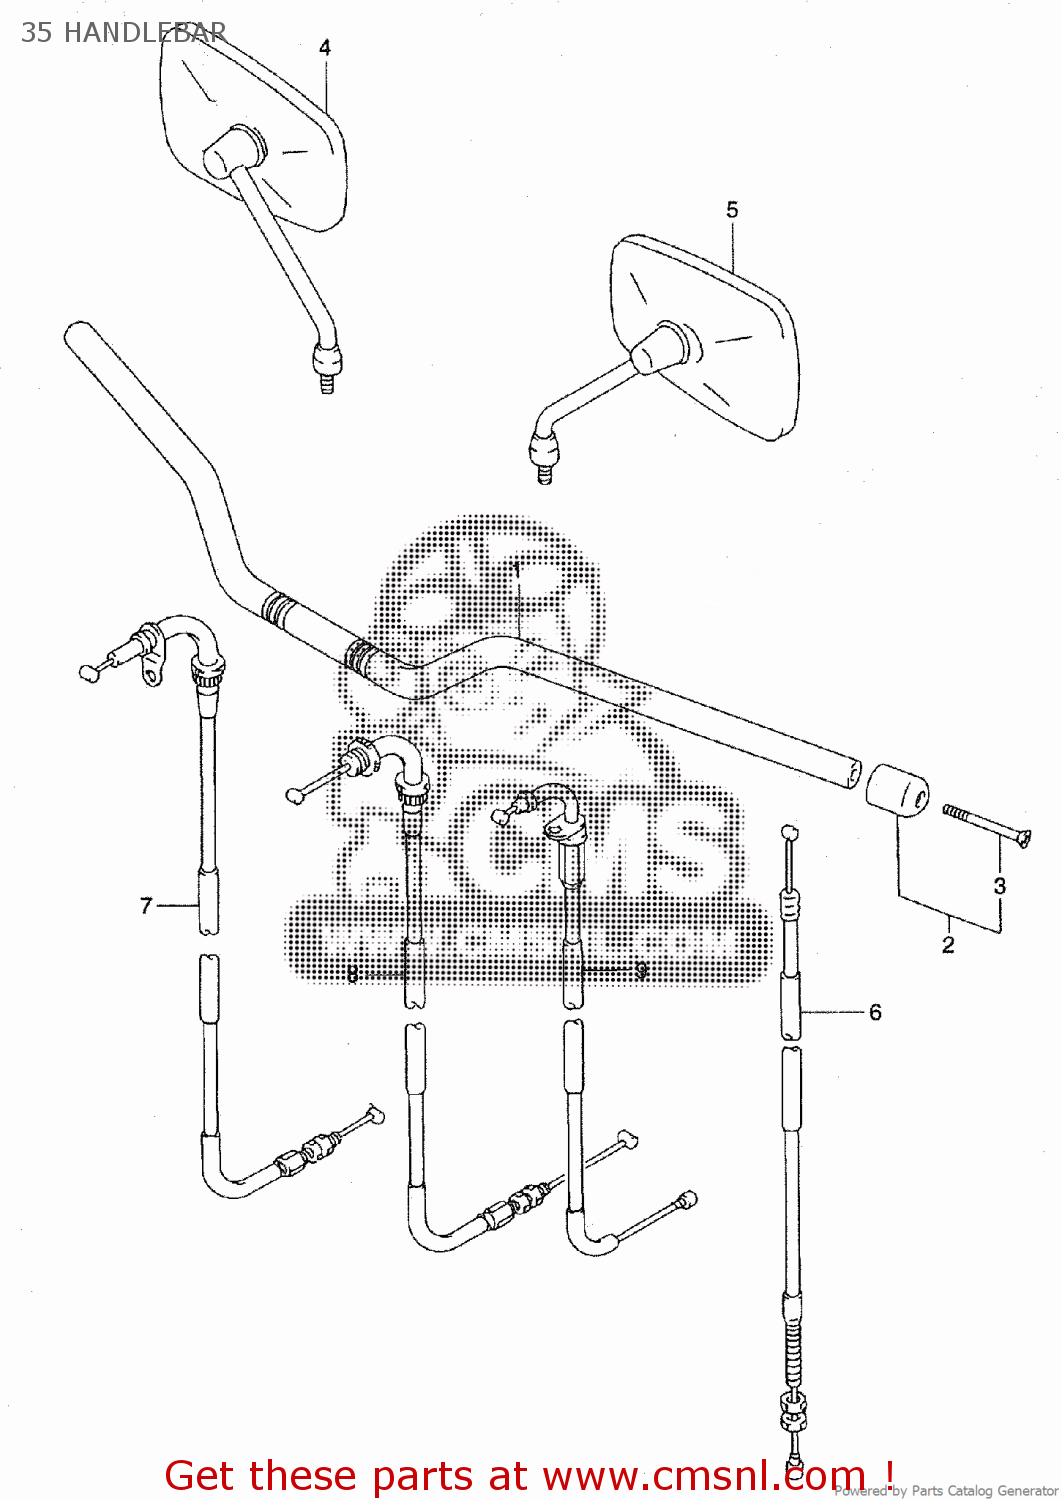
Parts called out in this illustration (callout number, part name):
2	BALANSGEWICHT.S
3	SCREW
4	MIRROR ASSY,RR VIEW,R
5	MIRROR ASSY,RR VIEW,L
6	CABLE ASSY,CLUTCH
9	CABLE,STARTER
